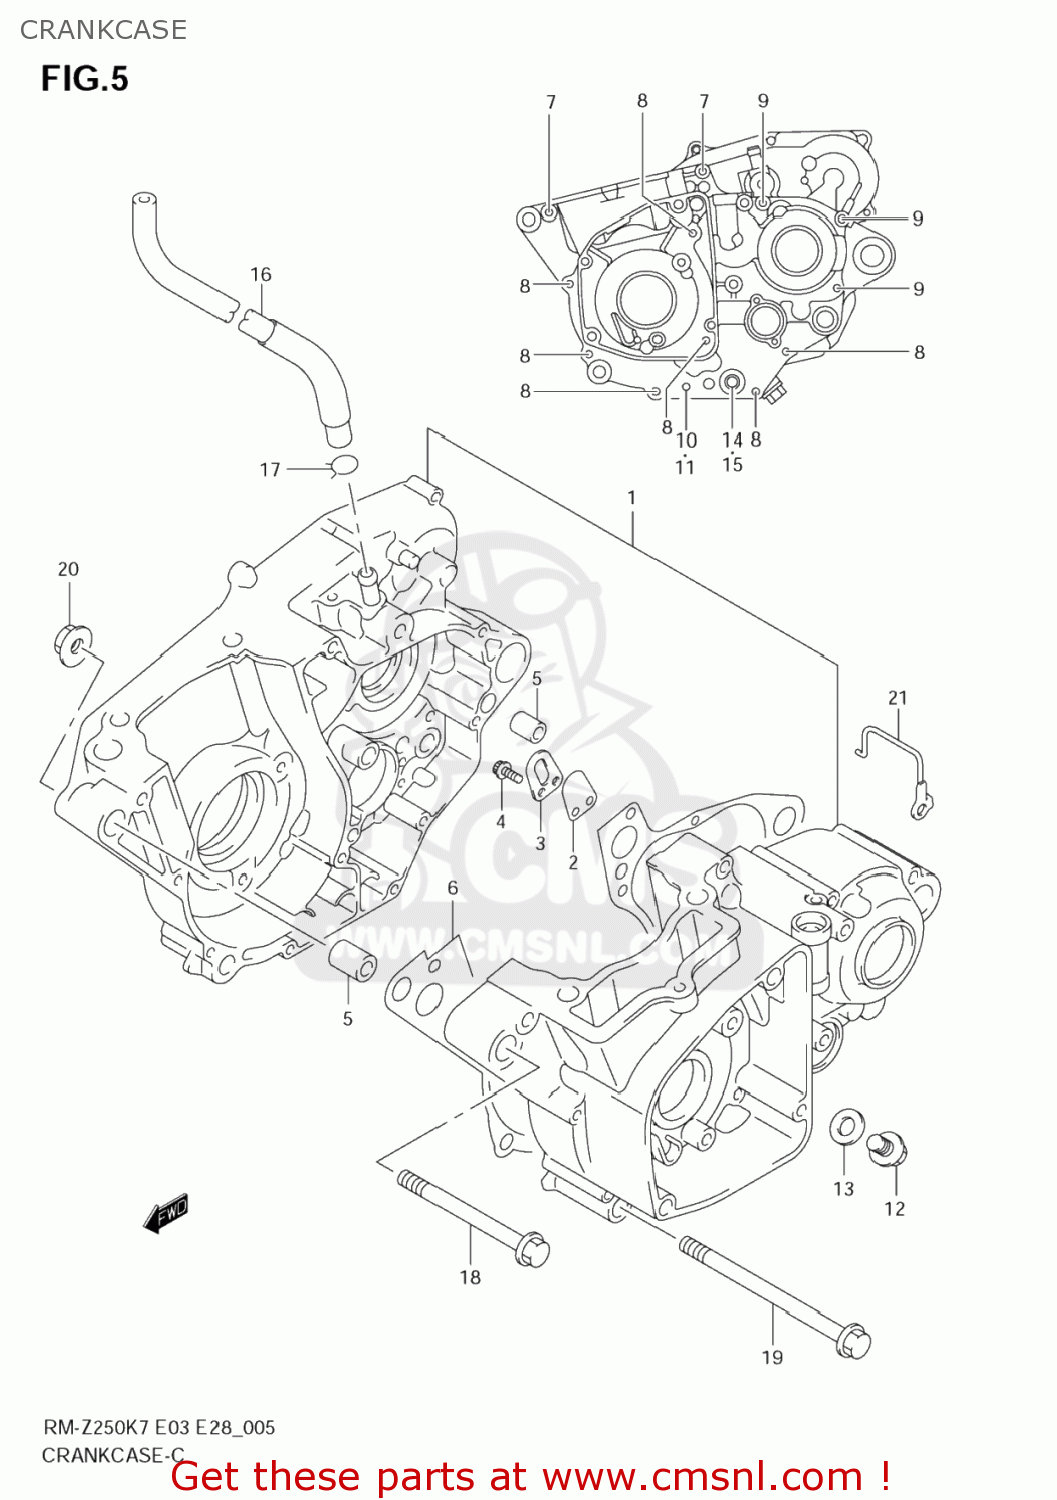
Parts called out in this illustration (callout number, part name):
1	CRANKCASE SET
2	VALVE,CRANKCASE REED
3	STOPPER,CRANKCASE REED VALVE
4	BOLT
5	PIN(10.4X13X18)
6	GASKET,CRANKCASE (NAS)
7	BOLT
8	BOLT
9	BOLT
10	BOLT
11	GASKET(6.2X11X1).2 (NAS)
12	PLUG(12X10)
13	GASKET(12.1X16.2X3.7) (NAS)
14	GASKET OILPLUG (NAS)
15	GASKET(16X22X2) (NAS)
16	HOSE,BREATHER
17	CLIP
18	BOLT(10X96)
19	BOLT(10X120)
20	NUT
21	GUIDE,CARBURETOR HOSE
